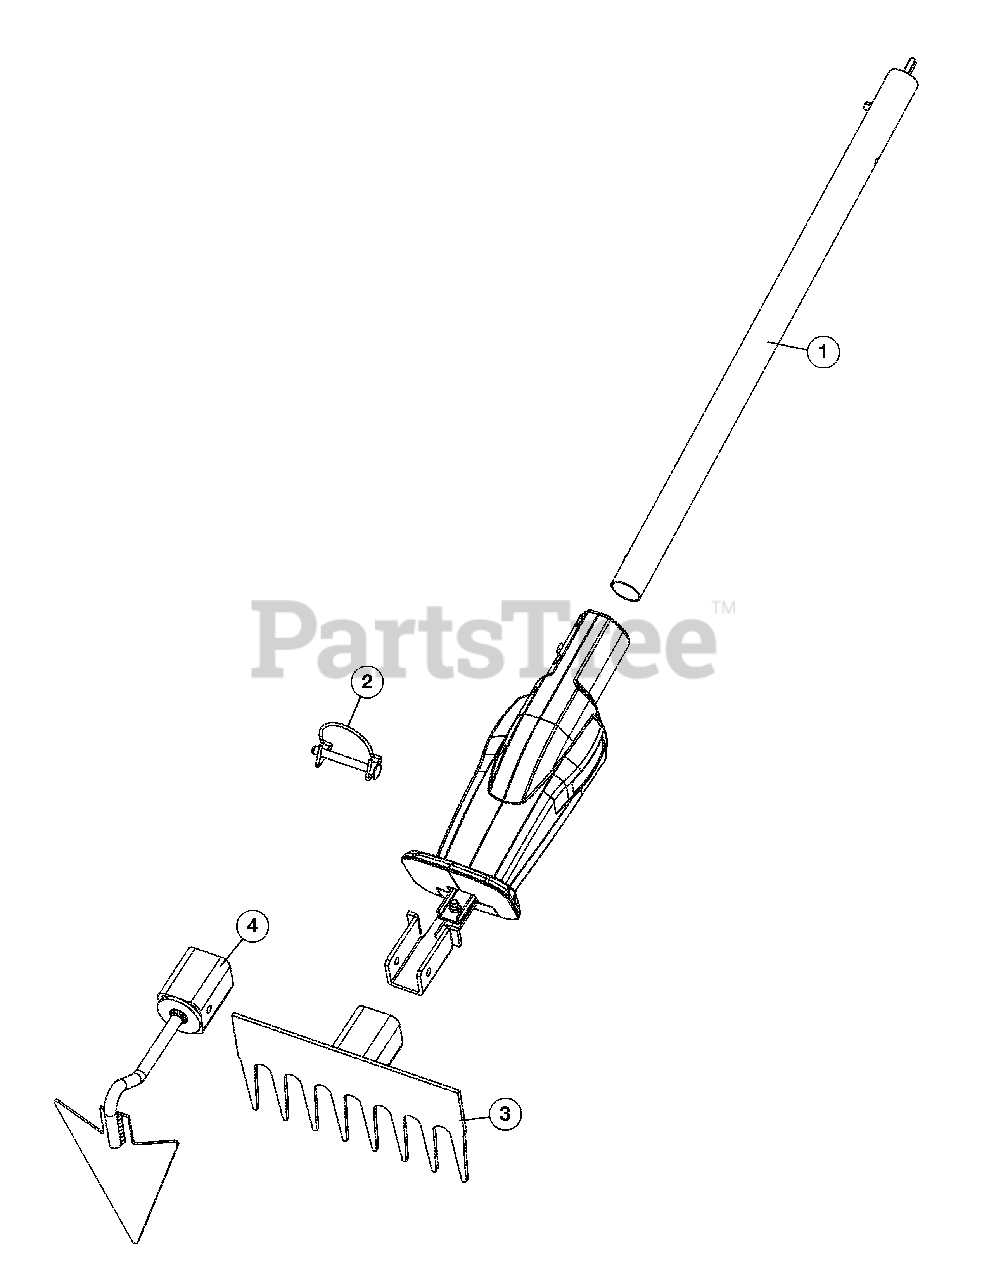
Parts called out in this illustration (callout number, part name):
1	Boom Assembly
2	Hinge Pin
4	Warren Hoe
